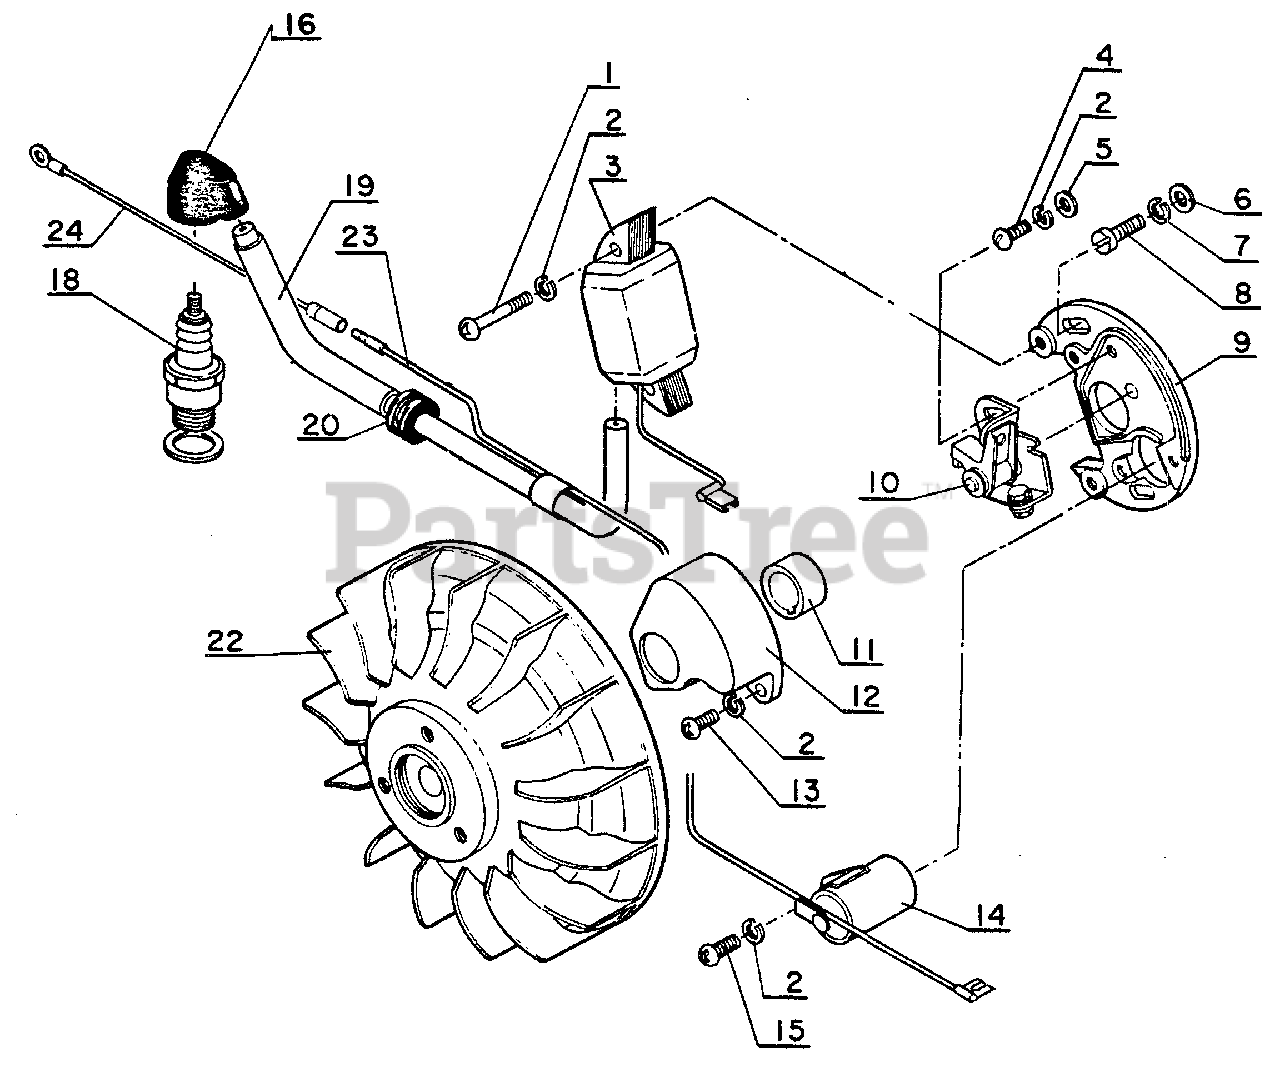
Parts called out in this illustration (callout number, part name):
1	SCREW 4×22
2	WASHER, SPRING 4 MM
3	COIL, IGNITION
4	SCREW 4×8
5	WASHER 4 MM
6	WASHER, FLAT 5.5×10×0.8
7	WASHER, SPRING 5
8	SCREW 5×15
9	CONTACT POINT SET
10	ARM, BREAKER
11	CAM
12	COVER
13	SCREW 4×12
14	CONDENSER
15	SCREW 4×8
16	CAP, SPARK PLUG
18	SPARK PLUG - BM6A
19	COVERED TUBE, SECONDARY CORD
20	BUSHING
22	FLYWHEEL
23	LEAD - GROUND
24	LEAD - GROUND
